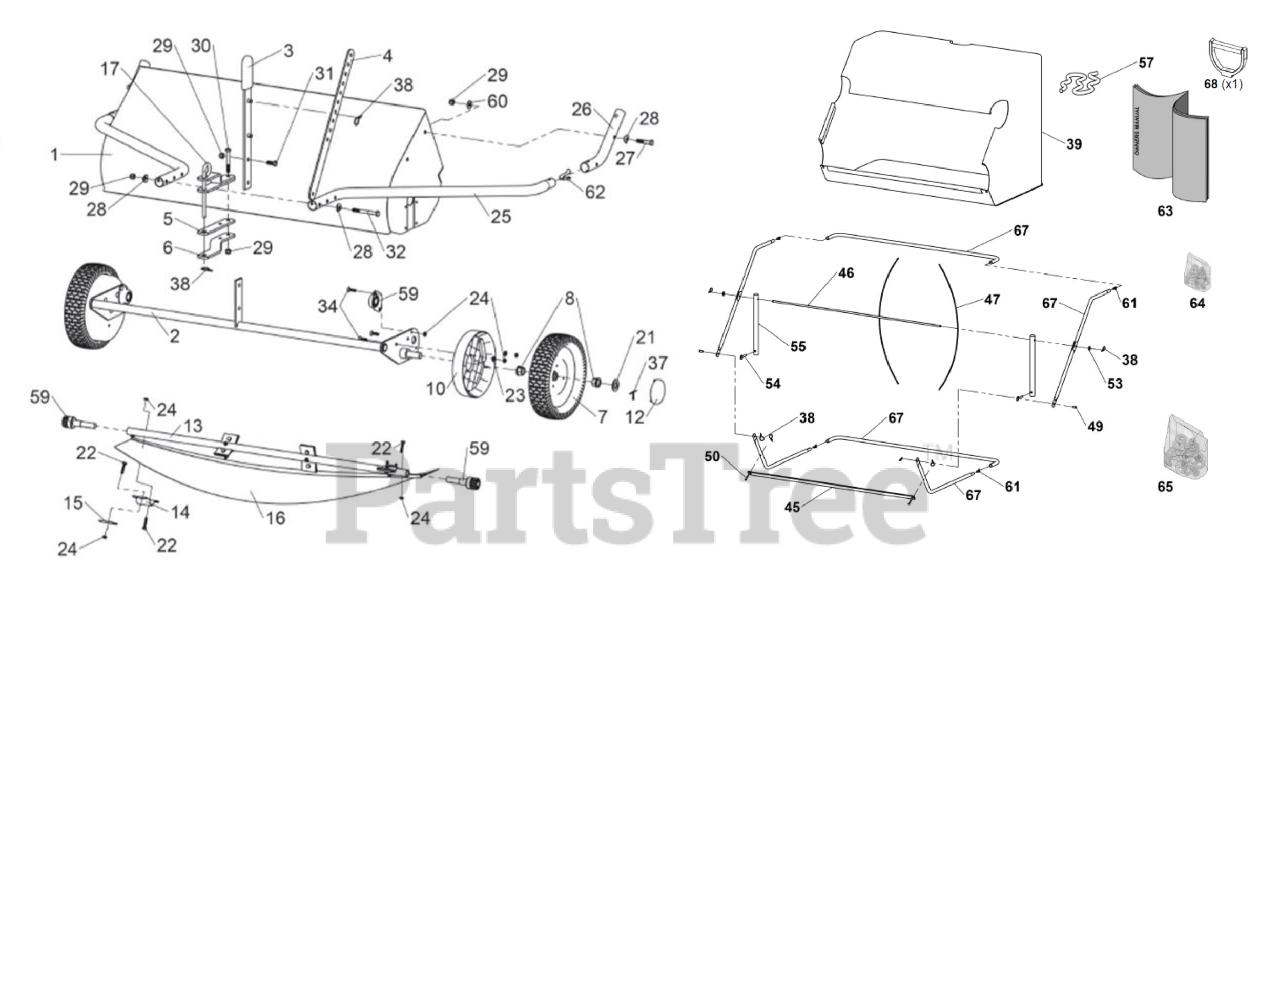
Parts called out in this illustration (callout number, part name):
1	Sweeper Housing
2	Height Adjustment
3	Height Adjustment Handle
4	Adjustment Lever
5	Flat Clevis Bar
6	Offset Clevis Bar
8	Wheel Bushing
13	Brush Axle
14	Brush Bracket
15	Brush Clamp
21	Washer 3/4" Sae
22	1/4-20 X 1-1/4 Hex Bolt
23	Flat Washer
24	1/4-20 Lock Nut
25	Long Hitch Tube
26	Short Hitch Tube
27	3/8-16 X 2 Hex Bolt
28	Curved Washer
29	3/8-16 Nyloc Nut
30	3/8-16 X 2-3/4 Hext Bolt
31	3/8-16 X 1 Hex Bolt
32	3/8-16 X 3-1/2 Hex Bolt
34	1/4-20 X 1 Carriage Bolt
37	Cotter Pin
39	Hopper Bag
45	Hopper Bar
47	Tension Rod
53	Washer 3/8" Uss
54	Quick Release Pin
55	Connecting Tube
59	Pinion Bearing Kit
60	Flat Washer
61	Snap Button
62	Snap Button
63	Owners Manual
64	Hitch Hardware Bag
65	Frame Hardware Bag
67	Hopper Frame Kit
68	Rope Handle
